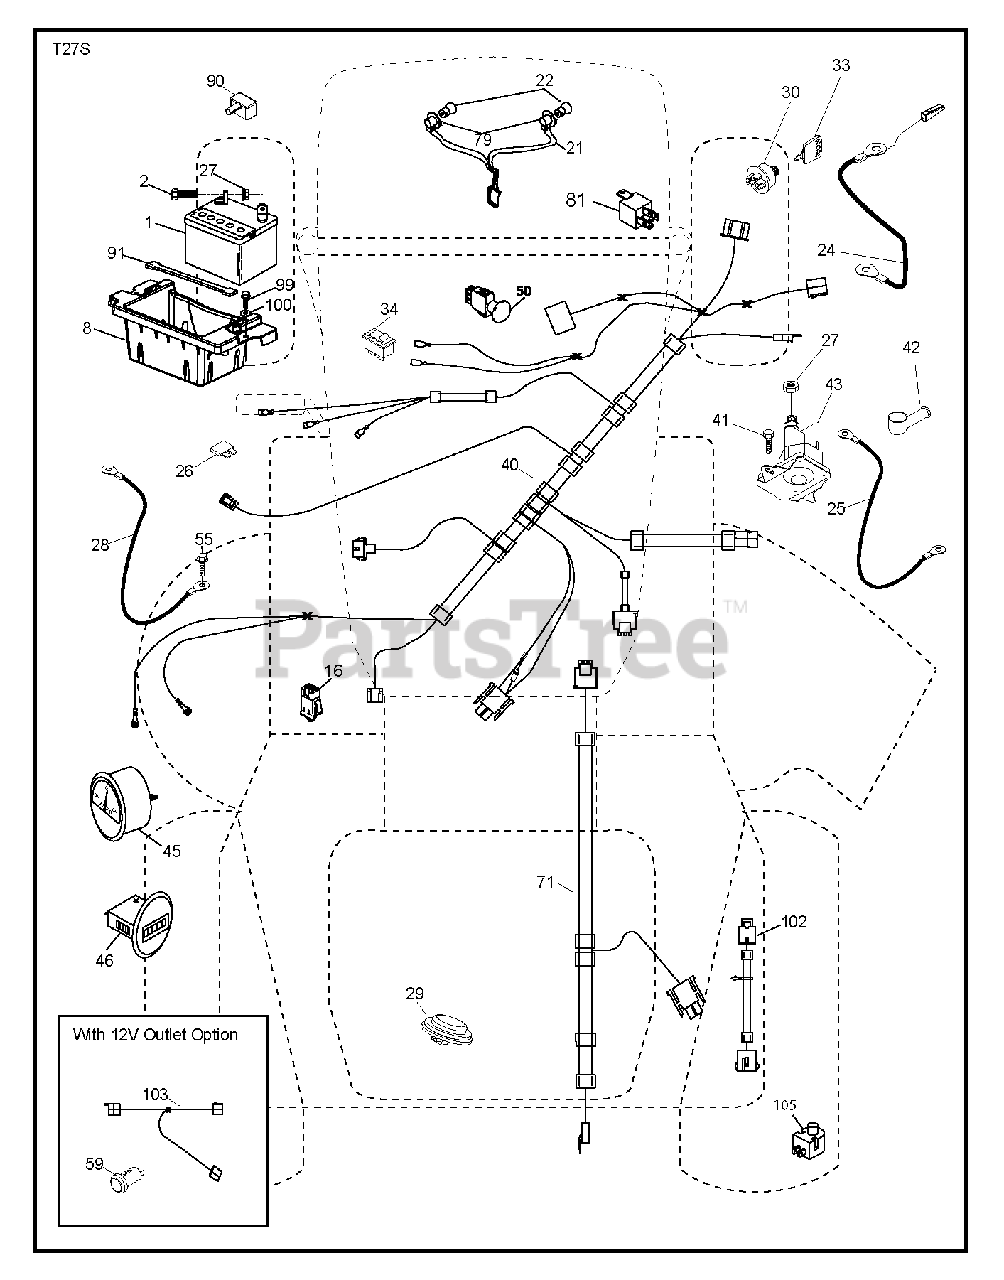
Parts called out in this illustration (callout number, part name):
2	BOLT LT
8	BOX, BATTERY MOUNT
16	SWITCH INTERLOOK PUSH-IN
21	HARNESS SOCKET LIGHT
22	LIGHTBULB
24	CABLE.BTRY.PSWRE.DSH.S
25	CABLE.STARTER.6G.BL/RED.17.5
26	FUSE 20AMP
28	CABLE GROUND 6 GA 21" 90T BLK
29	SWITCH.SEAT.DELTA.OPC.
30	IGNITION SWITCH
33	KEY/CHAIN.BLISTER.PACK.GEN.USA
34	SWITCH LT
40	HARNESS IGN. DASH
43	SOLENOID.W/BRASS.PLUNG
45	AMMETER.ROUND.SNAPIN
46	HOURMETER.ROUND.SNAPIN
50	PTO SWITCH
71	HARNESS-CHASSIS SUB
79	BULB HOLDER ASM.
81	RELAY HARNESS.SEALED
90	COVER.TERMINAL.BATTERY
91	STRAP, BATTERY MOUNT
99	SCREW HEXWSHR 1/4-20X3/4
102	HARNESS PIGTAIL PCH TEX ROS
105	REVERSE SWITCH
